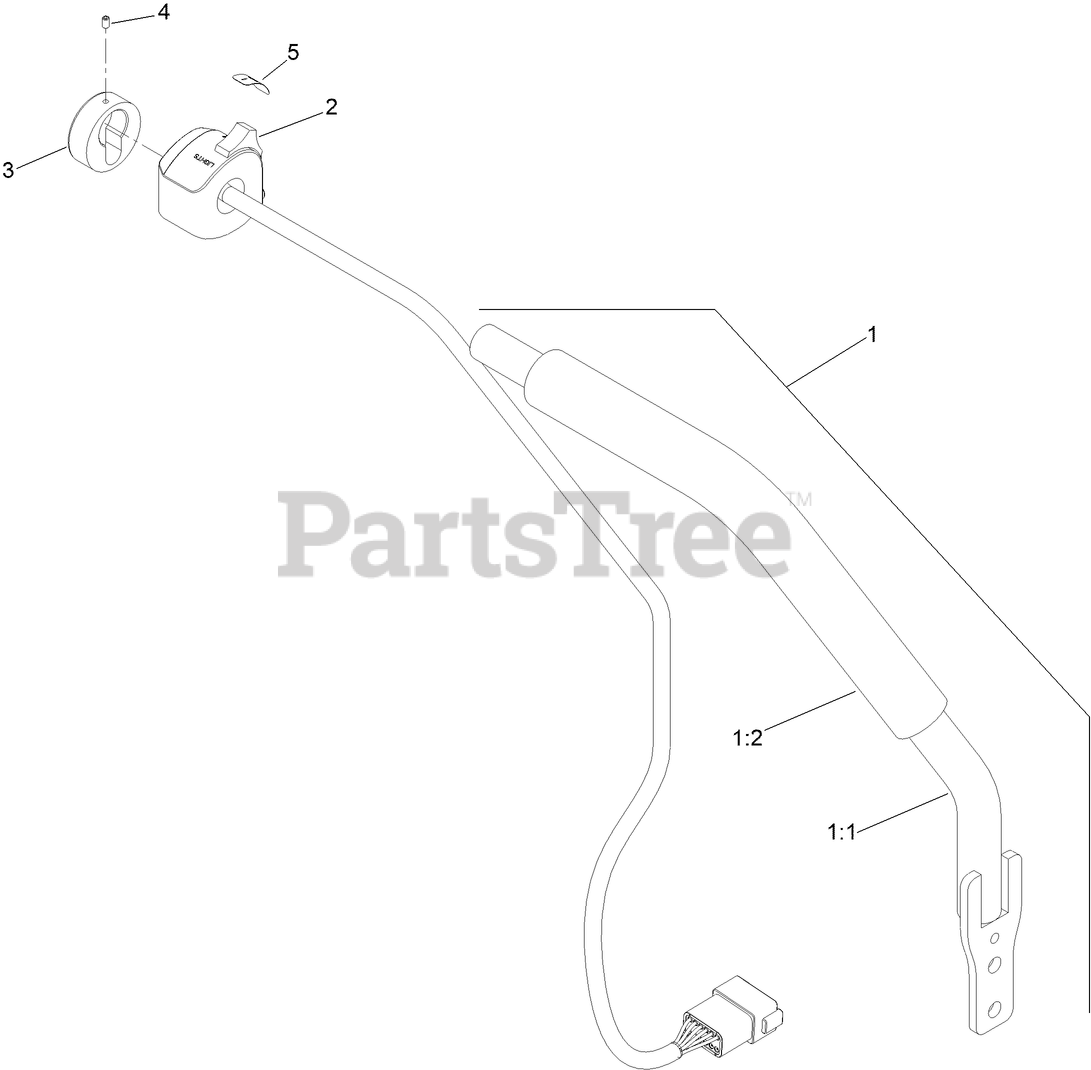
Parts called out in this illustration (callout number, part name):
1	LEVER ASM-FOAM, LH
1:1	LEVER ASM-LH [BLACK]
1:2	GRIP, CONTROL LEVER
2	SWITCH-COMBINATION ASSEMBLY
3	CAP-SWITCH
4	SCREW-SET
5	DECAL-LIGHTS
